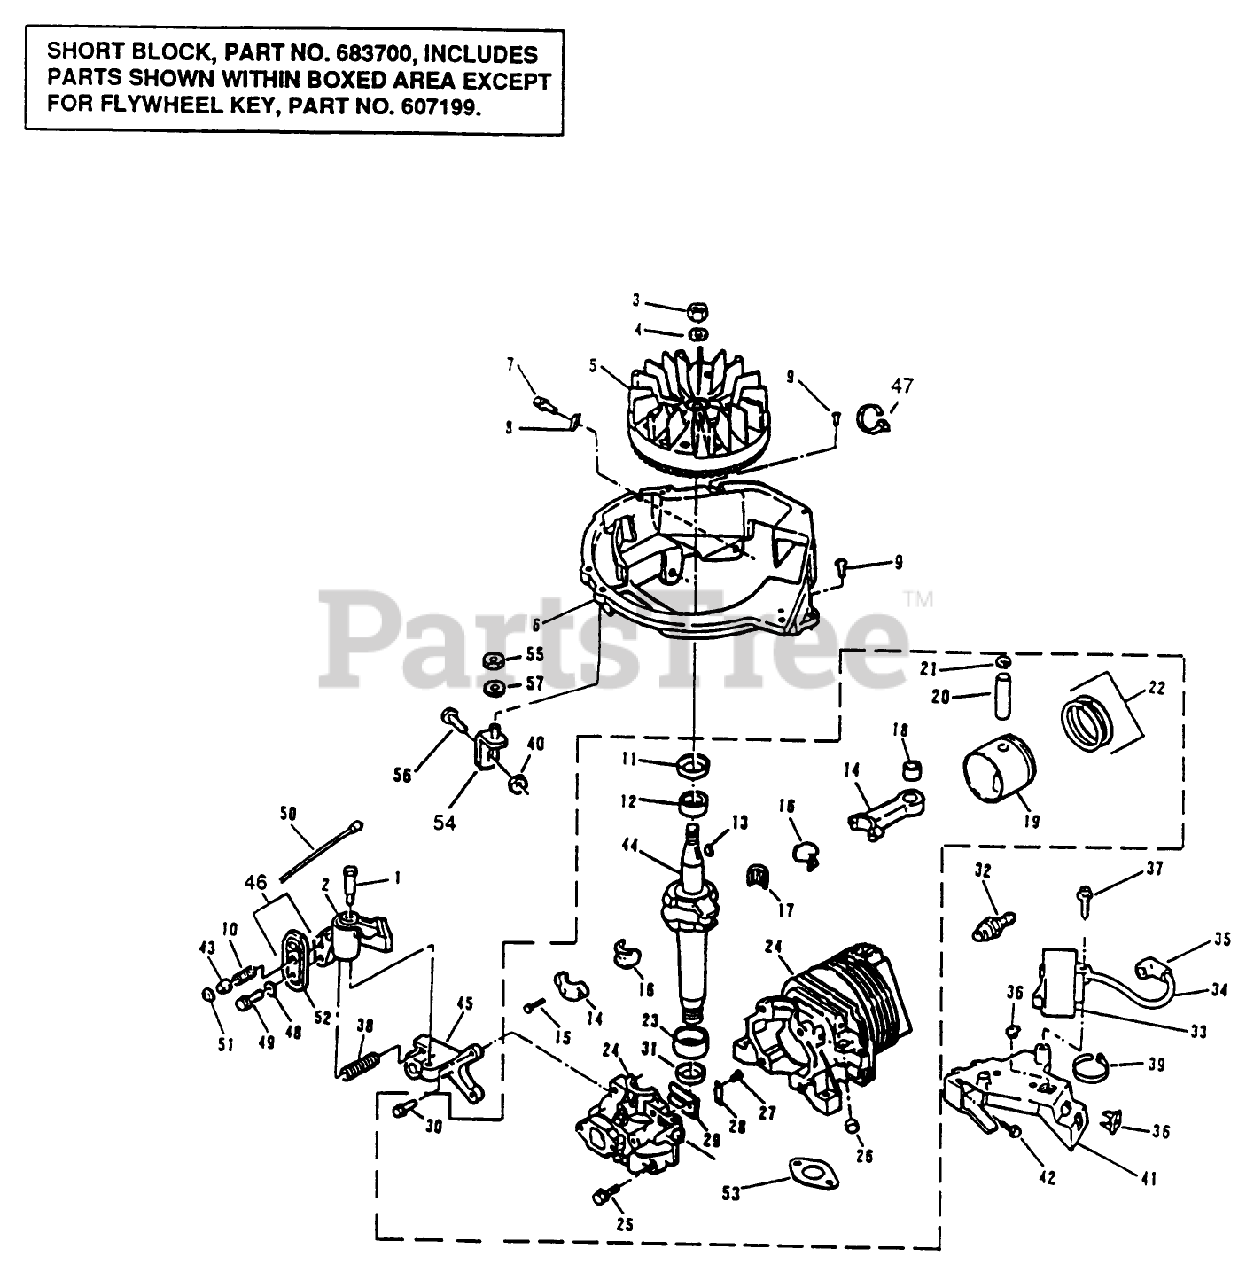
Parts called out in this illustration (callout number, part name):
1	SCREW-SHOULDER
3	NUT
5	FLYWHEEL ASSY F
6	BASE SHROUD F
7	SCREW-SEMS
9	SCREW F
10	SPRING
11	SEAL-OIL
12	BEARING V
13	KEY
14	Connecting Rod Assy (Inc. 15-18)
15	SCREW-HSH
16	LINER ASM
17	BEARING-NEEDLE
18	BEARING AY F
21	RING-RETAINING
23	BEARING V
25	SCREW-H.W.HD. F
26	PLUG-CORE VF
27	SCREW-HH
28	PLATE-BACKUP, REED
30	SCREW
31	SEAL-OIL
32	SPARK PLUG
34	HT LEAD&COVER XEV
35	COVER & TERM. AY S
36	NUT-CLIP
38	SPRING-BRAKE
39	TIE-CABLE
40	NUT-LOCK F
41	C.D. BRKT F
42	SCREW F
43	ACTUATOR-LEVER, BRAKE
45	BRACKET-BRAKE F
50	WIRE LEAD AY F
51	RETAINER S
54	BRACE AY F
55	LOCKNUT E
56	BOLT F
57	WASHER S
